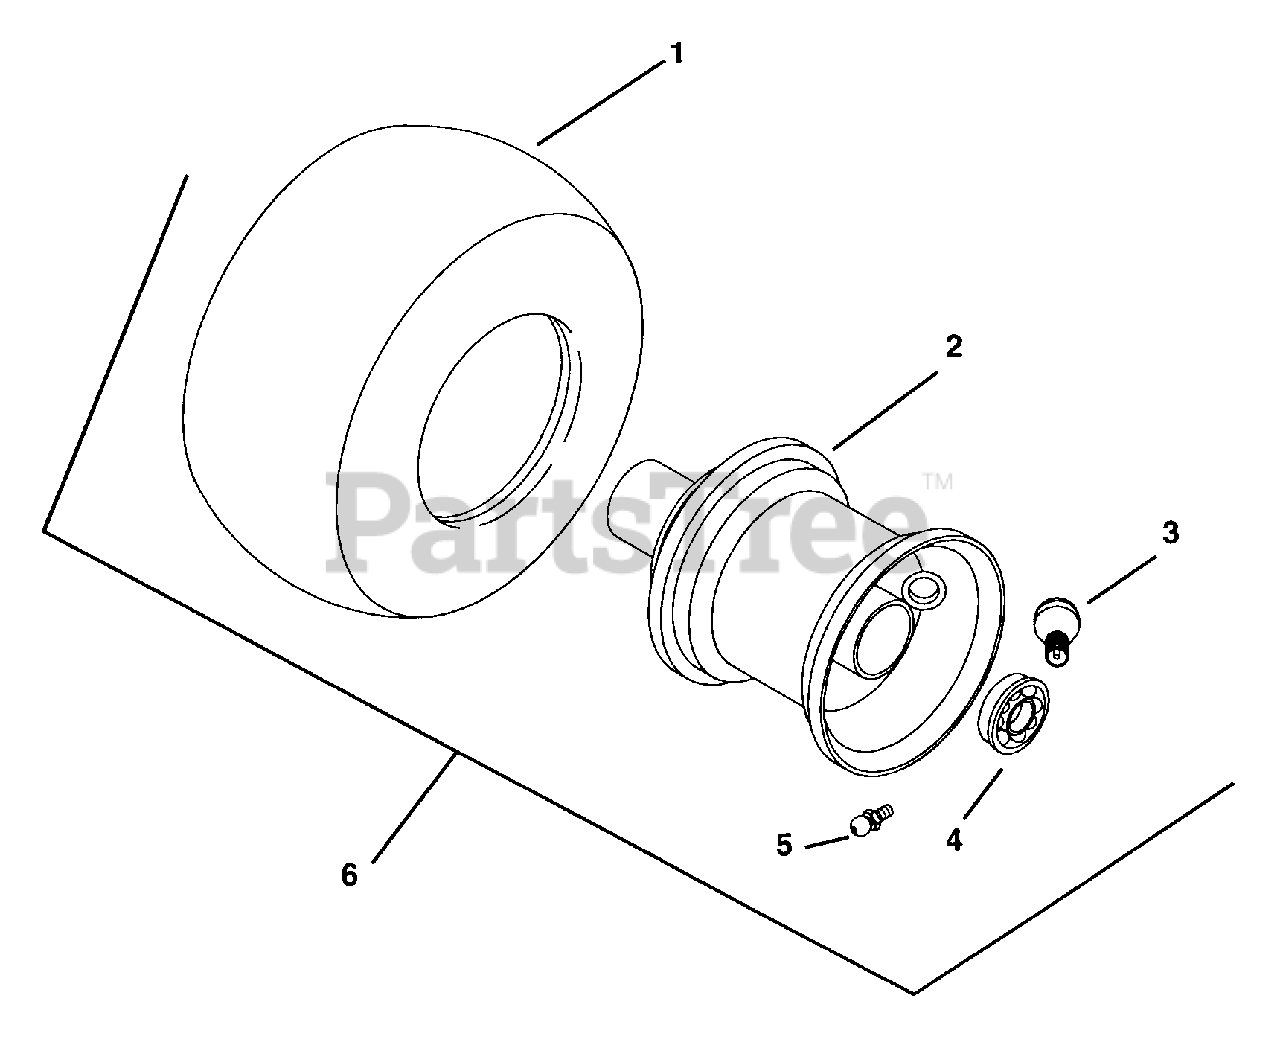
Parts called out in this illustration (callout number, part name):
1	Tire, 13 x 6.5-6
2	Rim-Assembly
3	Valve Stem Assembly
4	Radial Bearing
5	Fitting-Lube .25-28 x .256
6	Assembly, Wheel, 13 x 6.50-6
